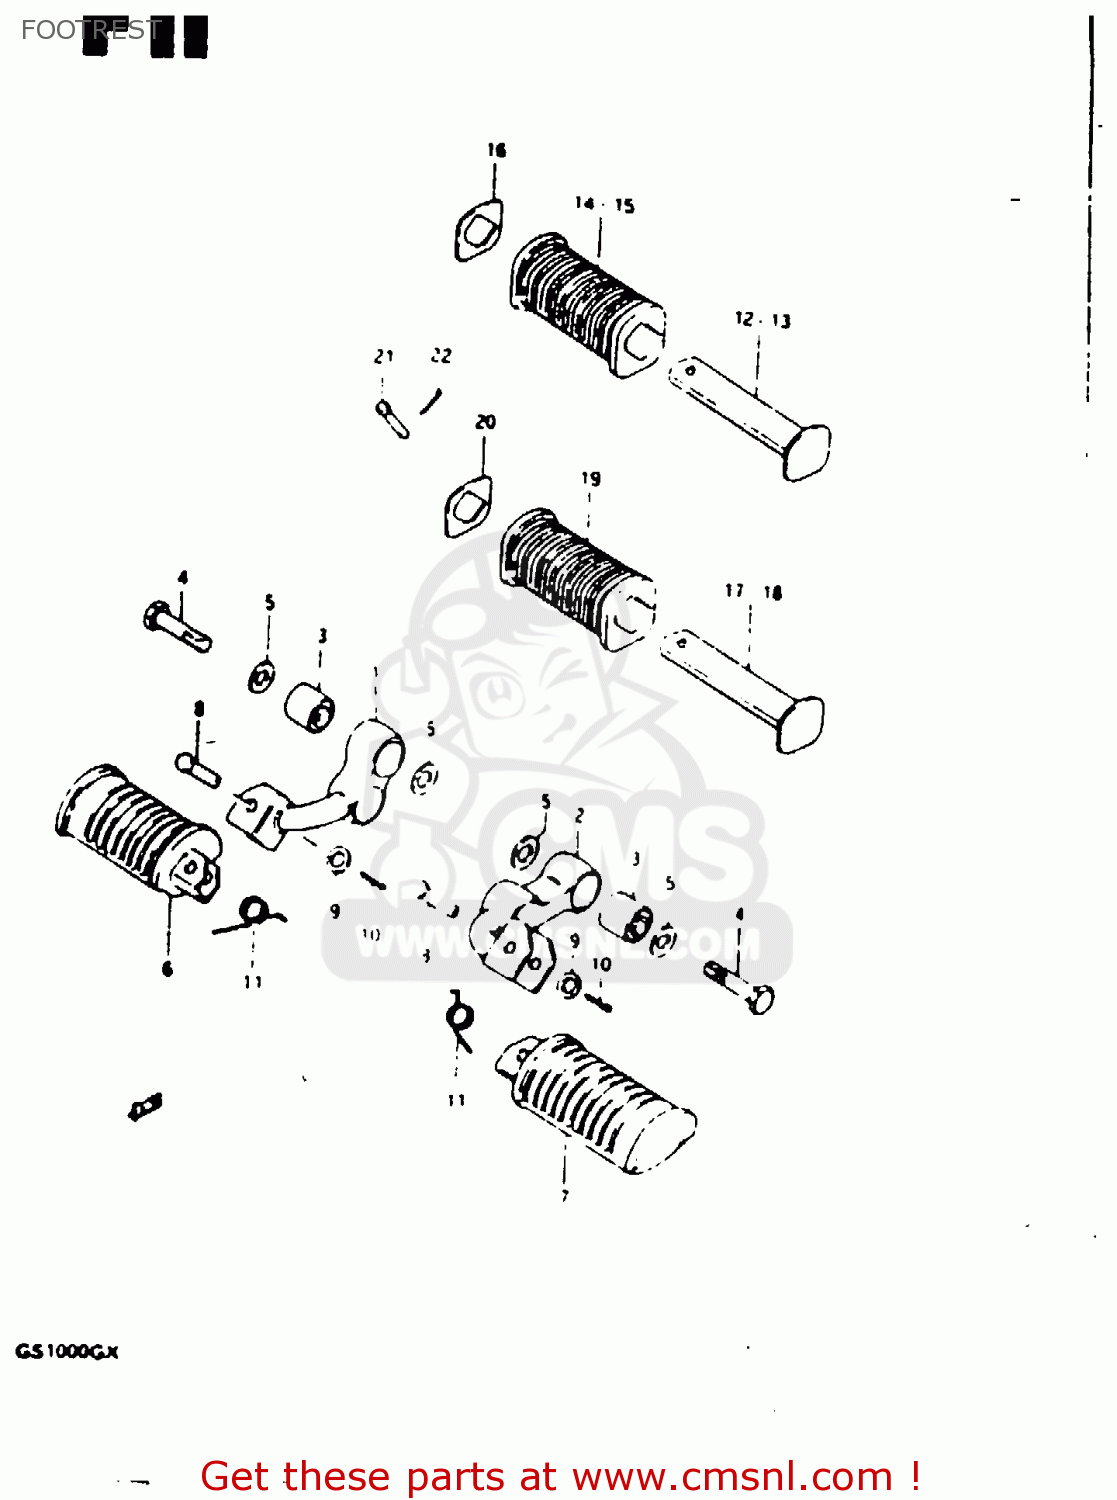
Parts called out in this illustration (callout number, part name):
1	BAR,FRONT FOOTREST,RIGHT
2	BAR,FRONT FOOTREST,LEFT
3	BUSH
4	BOLT
5	WASHER (10.1X21X2.3)
6	RUBBER,FRONT FOOTREST
7	FOOTREST
8	PIN
9	WASHER
10	PIN
11	SPRING
12	BAR,REAR FOOTREST
13	BAR,REAR FOOTREST
14	RUBBER,PILLION FOOTREST
15	RUBBER, LH
16	WASHER,REAR FOOTREST RUBBER
17	BAR,REAR FOOTREST,RIGHT
18	BAR,REAR FOOTREST,LEFT
19	RUBBER,PILLION FOOTREST
20	WASHER,PILLION FOOTREST RUBBER
21	PIN
22	PIN
